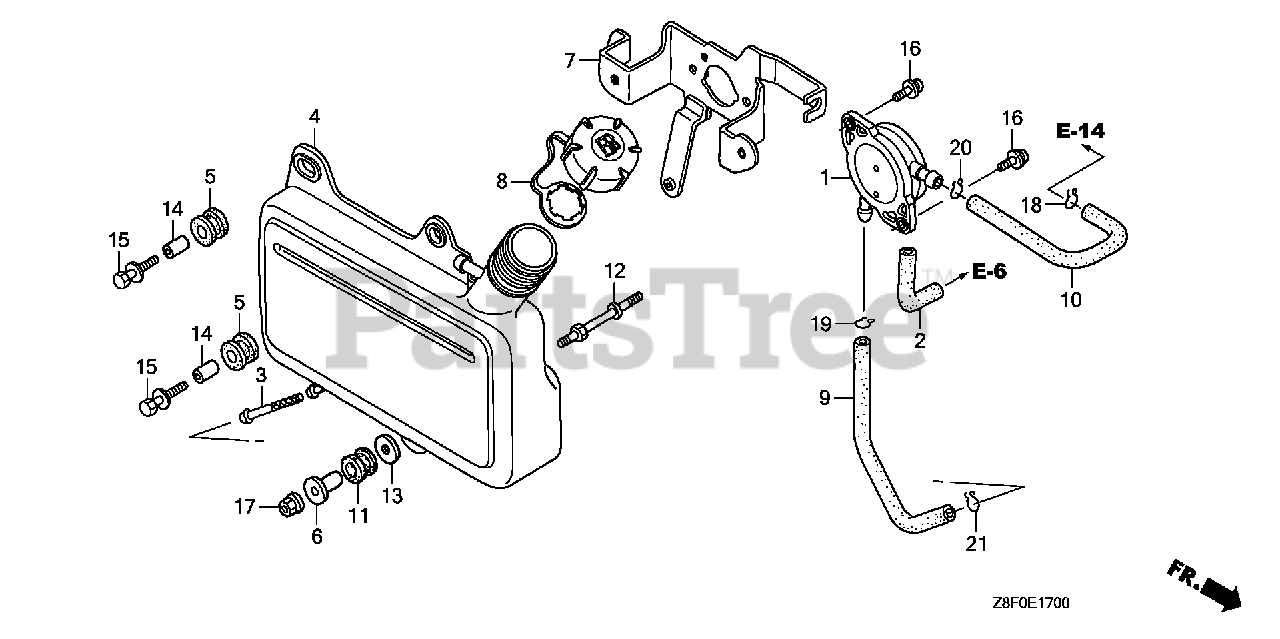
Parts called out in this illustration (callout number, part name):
1	PUMP ASSY., FUEL
2	TUBE, DIAPHRAGM
3	FILTER, FUEL
4	TANK KIT, FUEL
5	RUBBER B, TANK MOUNTING
6	COLLAR, FUEL TANK SETTING
7	STAY A, FUEL TANK
8	CAP ASSY., FUEL TANK
9	TUBE, FUEL TANK
10	TUBE, FUEL
11	CUSHION, RR. FENDER
12	BOLT, FUEL TANK STUD (H=30MM)
12	BOLT, STUD (FUEL TANK)
13	WASHER (6MM)
14	COLLAR (14X6.1)
15	BOLT-WASHER (6X25)
16	SCREW-WASHER (5X14)
17	NUT, FLANGE (6MM)
18	CLIP, TUBE (B8)
19	CLIP, TUBE (B10)
20	CLIP, TUBE (C9)
21	CLIP, TUBE (C11)
